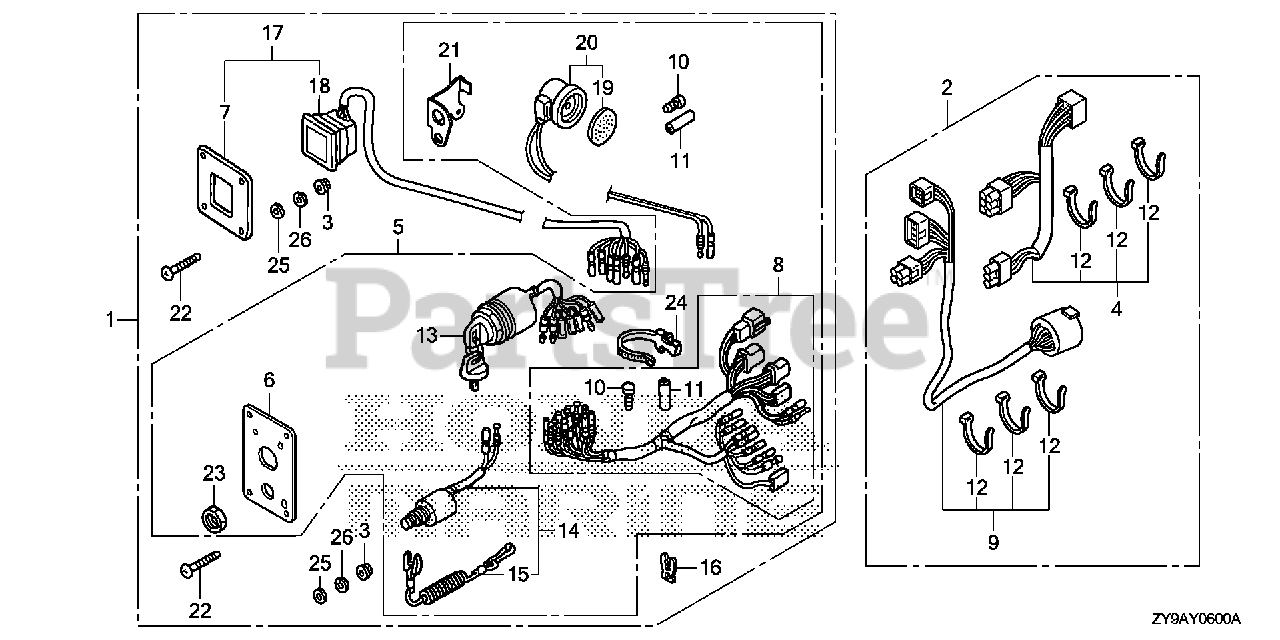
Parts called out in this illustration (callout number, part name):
1	PANEL KIT, SWITCH (4-LED) (B)
2	CABLE SET, PANEL INDICATOR (20FT)
2	CABLE SET, PANEL INDICATOR (25FT)
2	CABLE SET, PANEL INDICATOR (30FT)
3	NUT, FLANGE (5MM)
4	WIRE ASSY., INDICATOR (20FT)
4	WIRE ASSY., INDICATOR (25FT)
4	WIRE ASSY., INDICATOR (30FT)
5	PANEL ASSY., SWITCH
6	PANEL, CONTROL
7	PANEL, CONTROL
8	HARNESS ASSY., SWITCH PANEL
9	CABLE ASSY., SWITCH PANEL (25FT) (NHK MEC)
9	CABLE ASSY., SWITCH PANEL (20FT)
9	CABLE ASSY., SWITCH PANEL (25FT)
9	CABLE ASSY., SWITCH PANEL (30FT)
9	CABLE ASSY., SWITCH PANEL (20FT) (NHK MEC)
9	CABLE ASSY., SWITCH PANEL (30FT) (NHK MEC)
10	PLUG, CONNECTOR (INNER)
11	PLUG, CONNECTOR (OUTER)
13	SWITCH ASSY., COMBINATION
14	SWITCH ASSY., EMERGENCY STOP
15	WIRE, EMERGENCY
16	CLIP, EMERGENCY LOCK
17	PANEL ASSY., INDICATOR (4-LED)
18	LAMP ASSY., INDICATION (4-LED)
19	PLATE, TURN SIGNAL BUZZER
20	BUZZER, WARNING
21	BRACKET, BUZZER
22	SCREW, PAN (5X40)
23	NUT, HEX. (16MM)
24	BAND, WIRE HARNESS (150MM) (NATURAL)
25	WASHER, PLAIN (5MM)
26	WASHER, SPRING (5MM)
